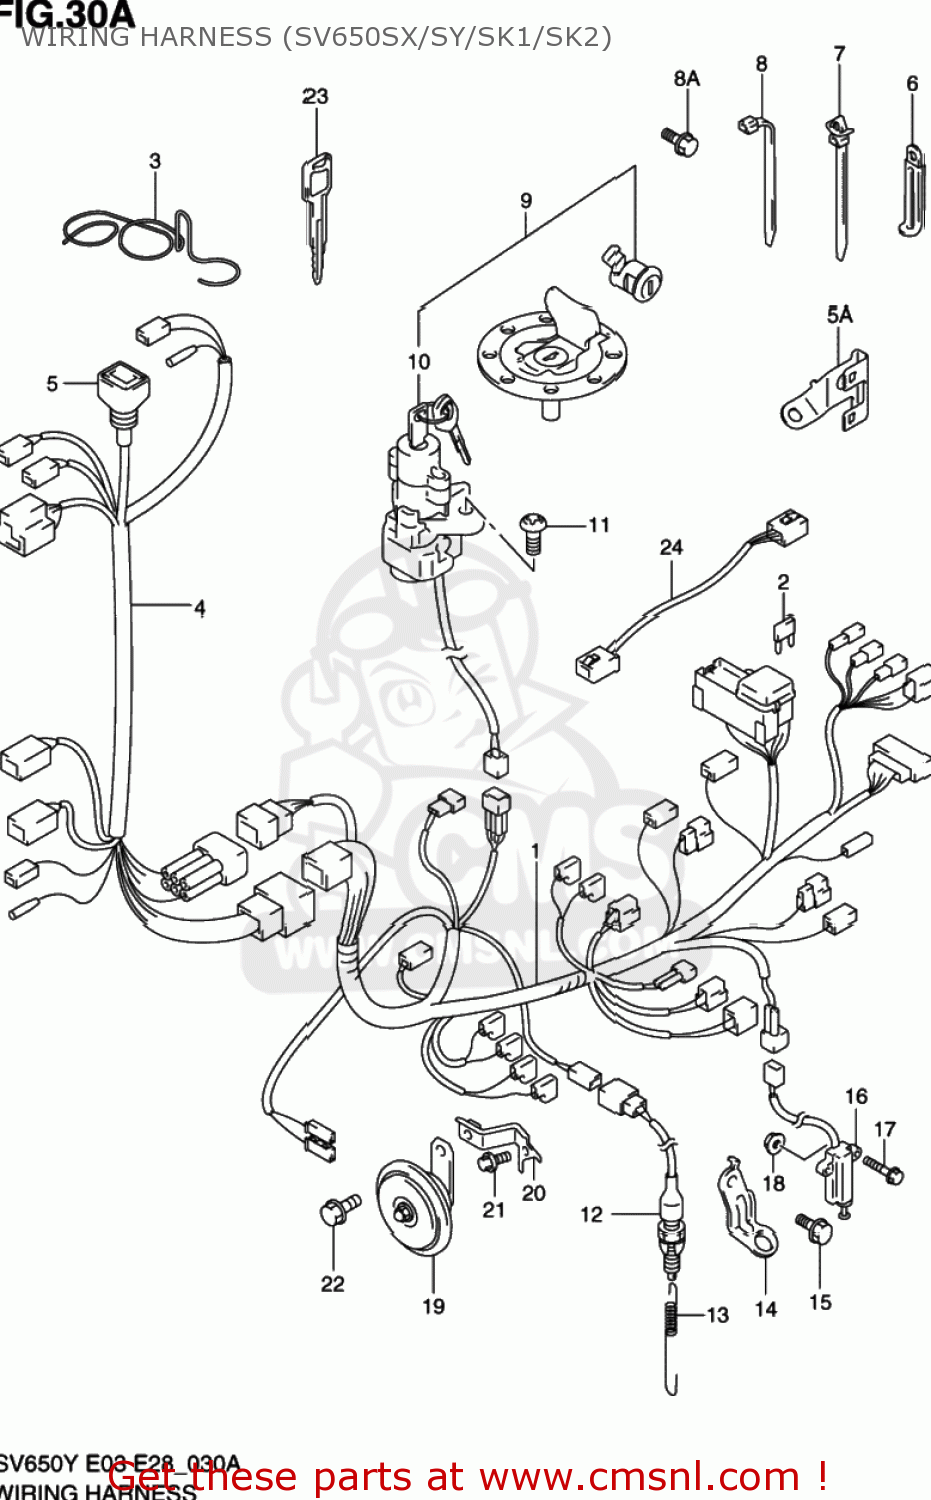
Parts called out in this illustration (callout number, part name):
1	HARNESS,WIRING NO.1
2	FUSE(10A)
3	GUIDE,WIRING HARNESS
4	HARNESS,WIRING NO.2
5	COVER,SPEEDOMETER COUPLER
5A	HOLDER,COUPLER
6	CLAMP(L:65)
7	CLAMP
8	CLAMP(L:125)
8A	BOLT
9	LOCK SET
10	LOCK ASSY,STEERING
11	BOLT(8X20)
12	SWITCH ASSY,STOP LAMP
13	SPRING
14	BRACKET,STOP LAMP SWITCH
15	BOLT
16	SWITCH ASSY,SIDE STAND
17	BOLT(6X20)
18	NUT
19	HORN ASSY
20	BRACKET,HORN
21	BOLT
22	BOLT
23	KEY,BLANK
24	WIRE,STARTER CONTROL
